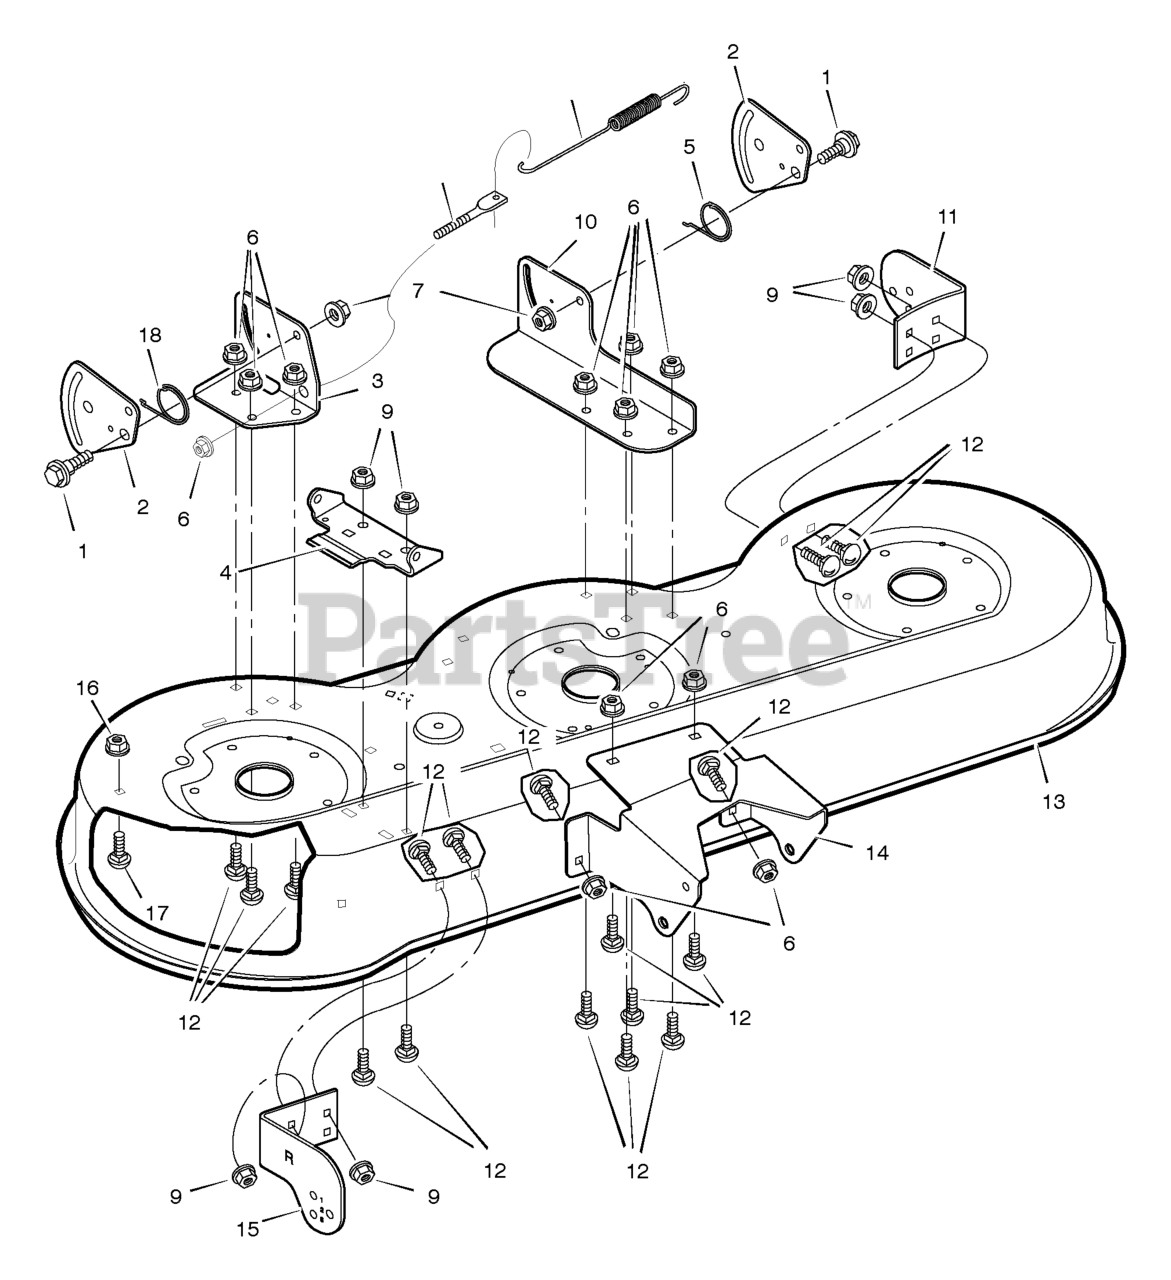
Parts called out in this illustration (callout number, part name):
1	Bolt, Shoulder
2	Plate, Suspension
3	Bracket, Right Rear
4	Bracket, Hinge
5	Spring, Left
6	Nut, Flange
7	Nut, Flange
9	Nut, Flange
10	Bracket, Left Lifter
11	Bracket, Left Gauge Wheel
12	Bolt, Carriage
13	Housing, Blade
14	Bracket, Front Deck
15	Bracket, Right Gauge Wheel
16	Retainer
17	Bolt, Carriage
18	Spring, Right
23	Rod, Adjuster
24	Spring, Extension
